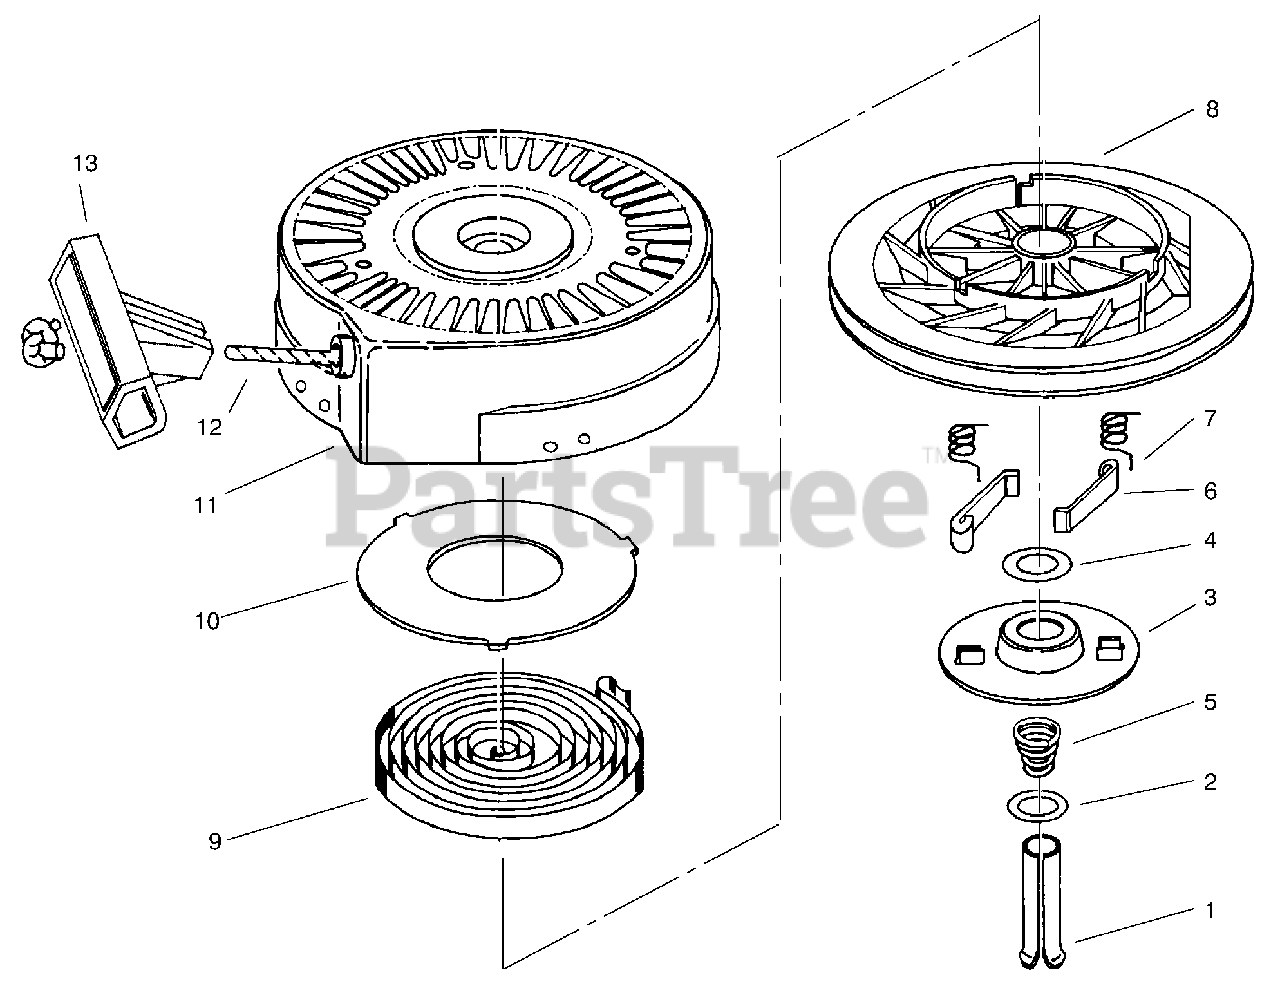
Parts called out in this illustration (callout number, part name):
1	Spring Pin (Incl. Ref. #4)
3	Retainer
5	Brake Spring
6	Starter Dog
7	Dog Spring
8	Pulley Assembly (Incl. Ref. #9 & 10)
9	Rewind Spring
10	Spring Cover
11	Starter Housing Assembly
12	Starter Rope
13	Starter Handle
